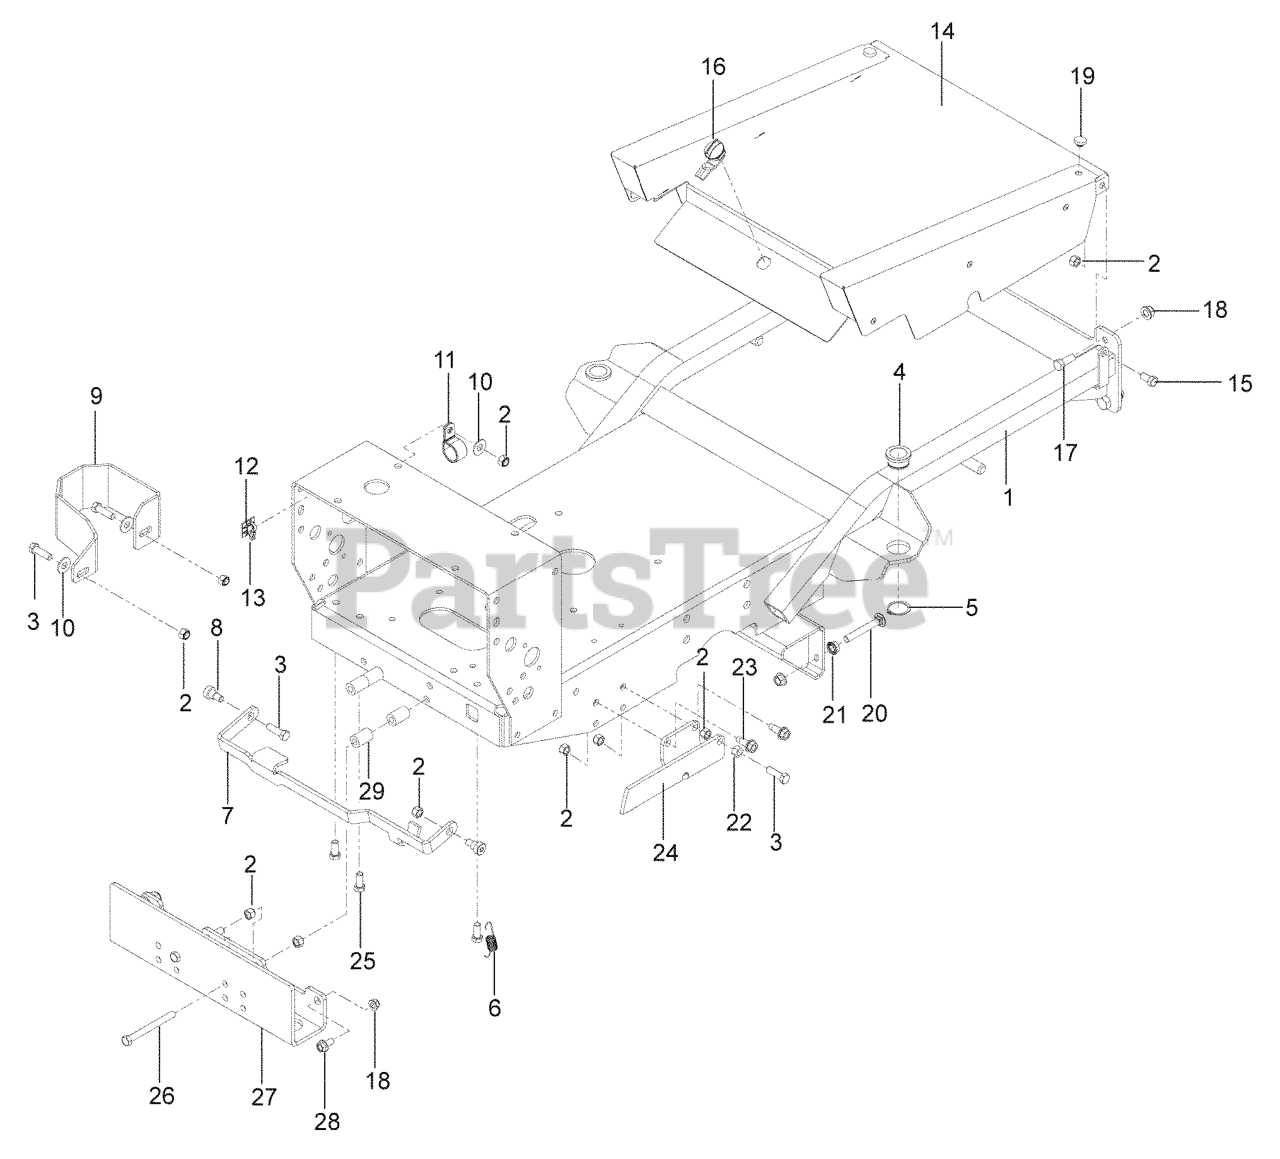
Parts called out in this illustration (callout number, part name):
1	CHASSIS WLDT ORANGE
2	NUT 3/8-16 NYLOC
3	HCS 3/8C X 1 1/4 GR5
4	BUSHING, BRONZE HOC
5	SNAP RING 1.25
6	SPRING, EXTENSION
7	BAR, THROWOUT OR
8	SB 3/8-16 X 3/8 SKT HD ZD
9	GUARD FILTER PAINTED
10	WASHER 3/8 FLAT
12	MOUNTING BLOCK CABLE TIE
13	TIE, PLASTIC
14	COVER, ASM, CENTER
15	SCREW 3/8C X 3/4 HEX CAP
16	LATCH, SHORT WING
17	HCS 1/2-13 X 1-1/4
18	NUT, 1/2-13 HEX FLG NYLOC ZD
19	GROMMET, BUMPER
20	RHSNB 3/8-16 x 2¾
21	NUT 3/8C WHIZ
22	NUT 3/8-16
23	BOLT 3/8-16 X 1.0
24	SUPPORT PLATE, P. BRAKE RH BLK
25	HCS 3/8-16 X 7/8 GR 5 ZD
26	HCS3/8-16.X
28	HHFS 1/2-13 X 1 GR5 ZD
